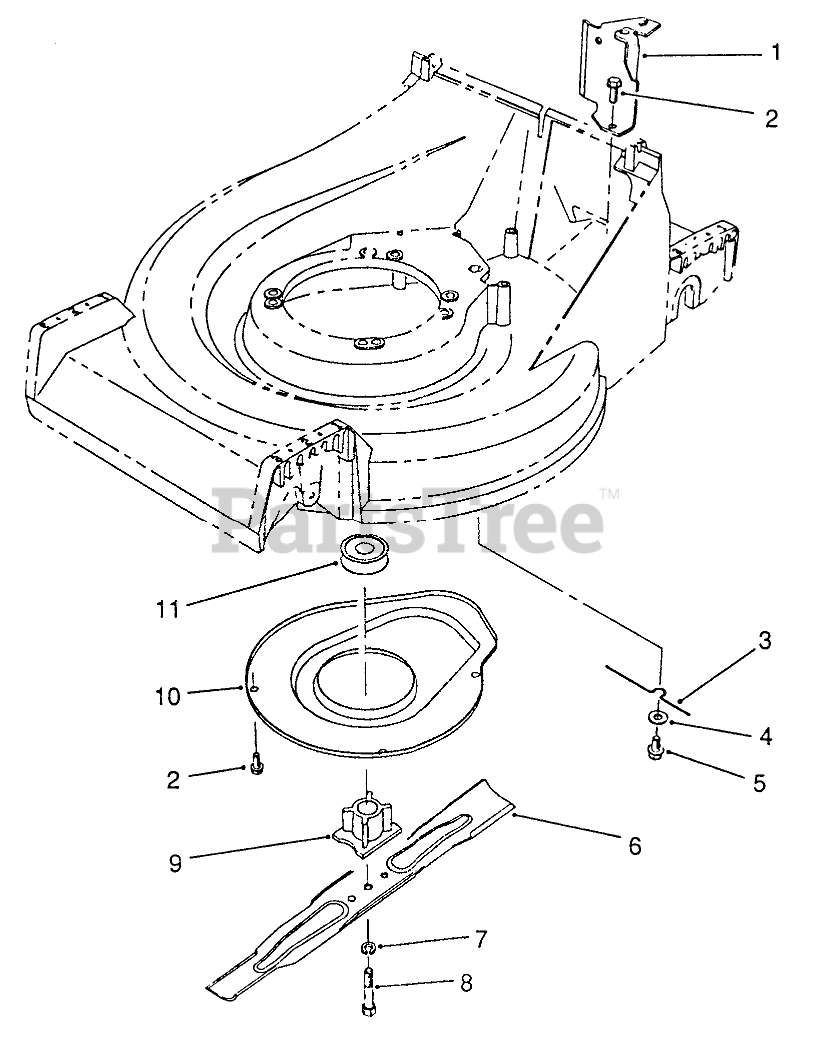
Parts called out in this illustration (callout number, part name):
1	Bracket-Cable Support
2	SCREW-HWHTF
3	RETAINER-BELT
4	WASHER-FLAT
5	SCREW-HHFTF
6	Key
7	WASHER-LOCK
8	SCREW-BLADE
9	BLADE RETAINER
10	Cover
11	PULLEY-DRIVE, ZONE START
